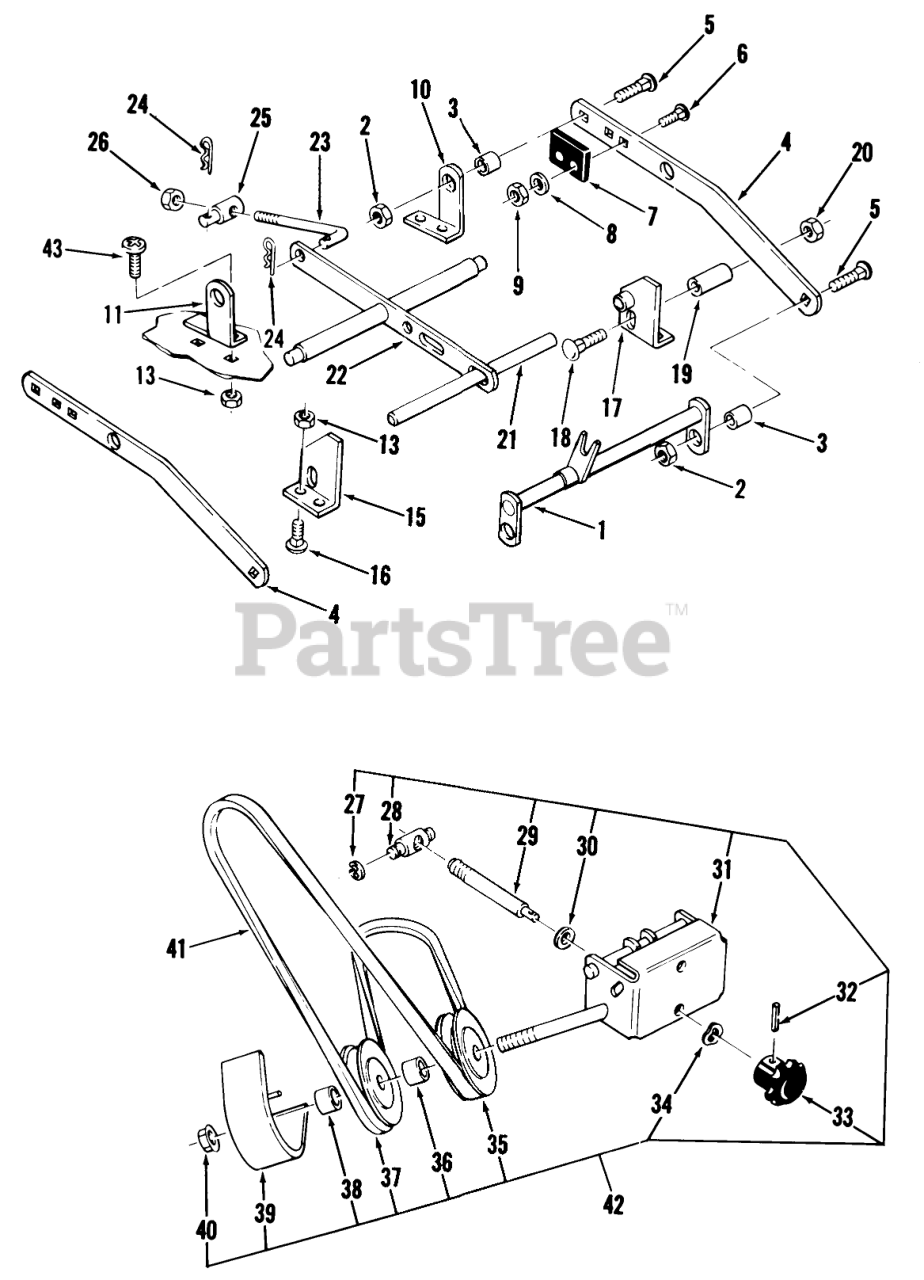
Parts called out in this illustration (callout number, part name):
1	Hitch
2	LOCKNUT-FLANGE
3	SPACER
4	Bar Draft
5	Bolt
6	Bolt-Carriage
7	Metal Bumper
8	BUMPER
9	Nut
10	LH Rear Bracket
11	Rear Bracket RH
13	Nut
15	Front Bracket RH
16	Bolt-Carriage
17	Front Bracket LH
18	CARRIAGE BOLT -4
19	SPACER-BEARING
20	Nut
21	Front Shaft
22	Leveler
23	ROD-LEVEL ADJUST
24	Hairpin
25	TRUNNION-LIFT
26	NUT
27	RING-RETAINING
28	TRUNNION-DOUBLE
29	ROD ADJ
30	Washer
31	Front Support
32	PIN-ROLL
33	KNOB-ADJUSTMENT
34	Spring Washer
35	Pulley-V
36	SPACER
37	PULLEY-FLAT IDLER
38	SPACER-OUTER
39	Belt Cover
40	Nut 3/4-16 MF
41	Drive Belt
42	ASM-SUPPORT,IDLER
43	SCREW
